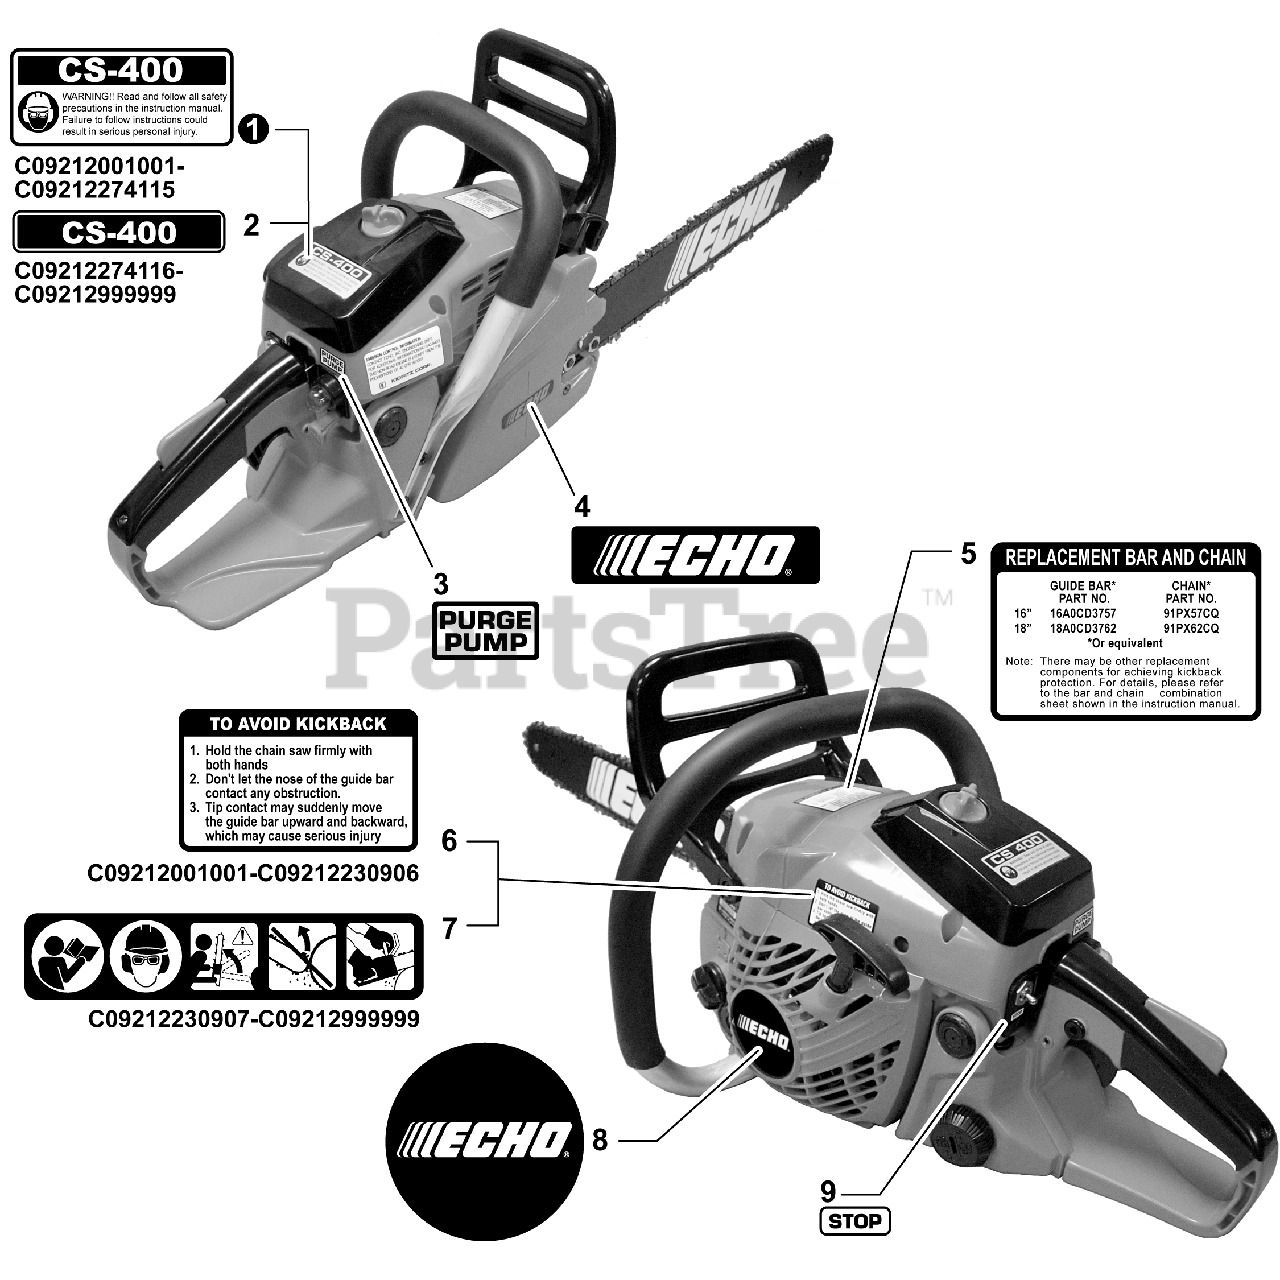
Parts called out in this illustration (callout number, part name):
1	LABEL - MODEL CS-400
2	LABEL - MODEL CS-400
3	LABEL, PURGE PUMP
4	LABEL, ECHO
5	LABEL, BAR & CHAIN
6	LABEL, UL - KICK BACK
7	LABEL, CAUTION
8	LABEL, ECHO
9	LABEL, STOP
